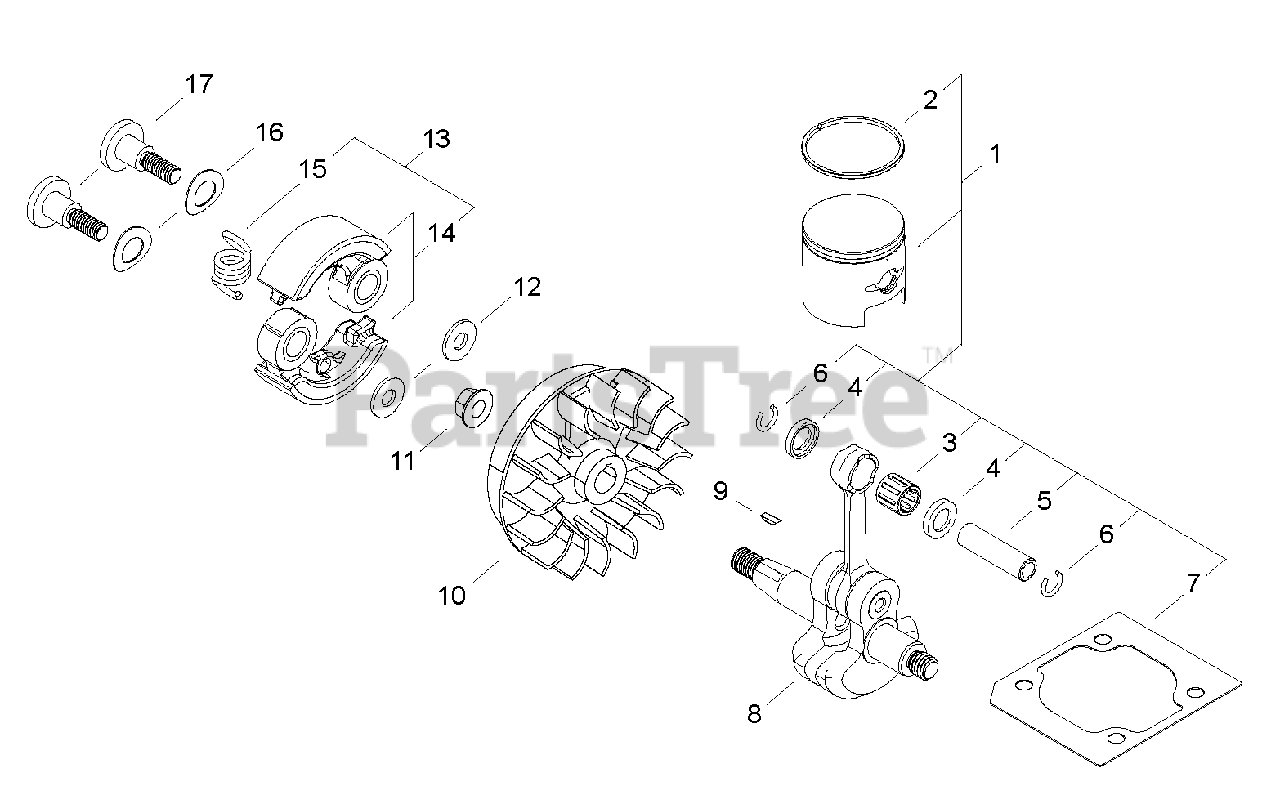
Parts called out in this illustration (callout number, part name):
1	PISTON KIT
2	RING, PISTON
3	BEARING, NEEDLE - 8
4	SPACER, PISTON
5	PIN, PISTON
6	RING, RETAINING
7	GASKET, CYLINDER
8	CRANKSHAFT ASSY
9	KEY - 3X10
10	FLYWHEEL
11	NUT - 8
12	WASHER - 6
13	CLUTCH KIT
14	SHOE, CLUTCH
15	SPRING, CLUTCH
16	WASHER - SPRING
17	BOLT, CLUTCH
